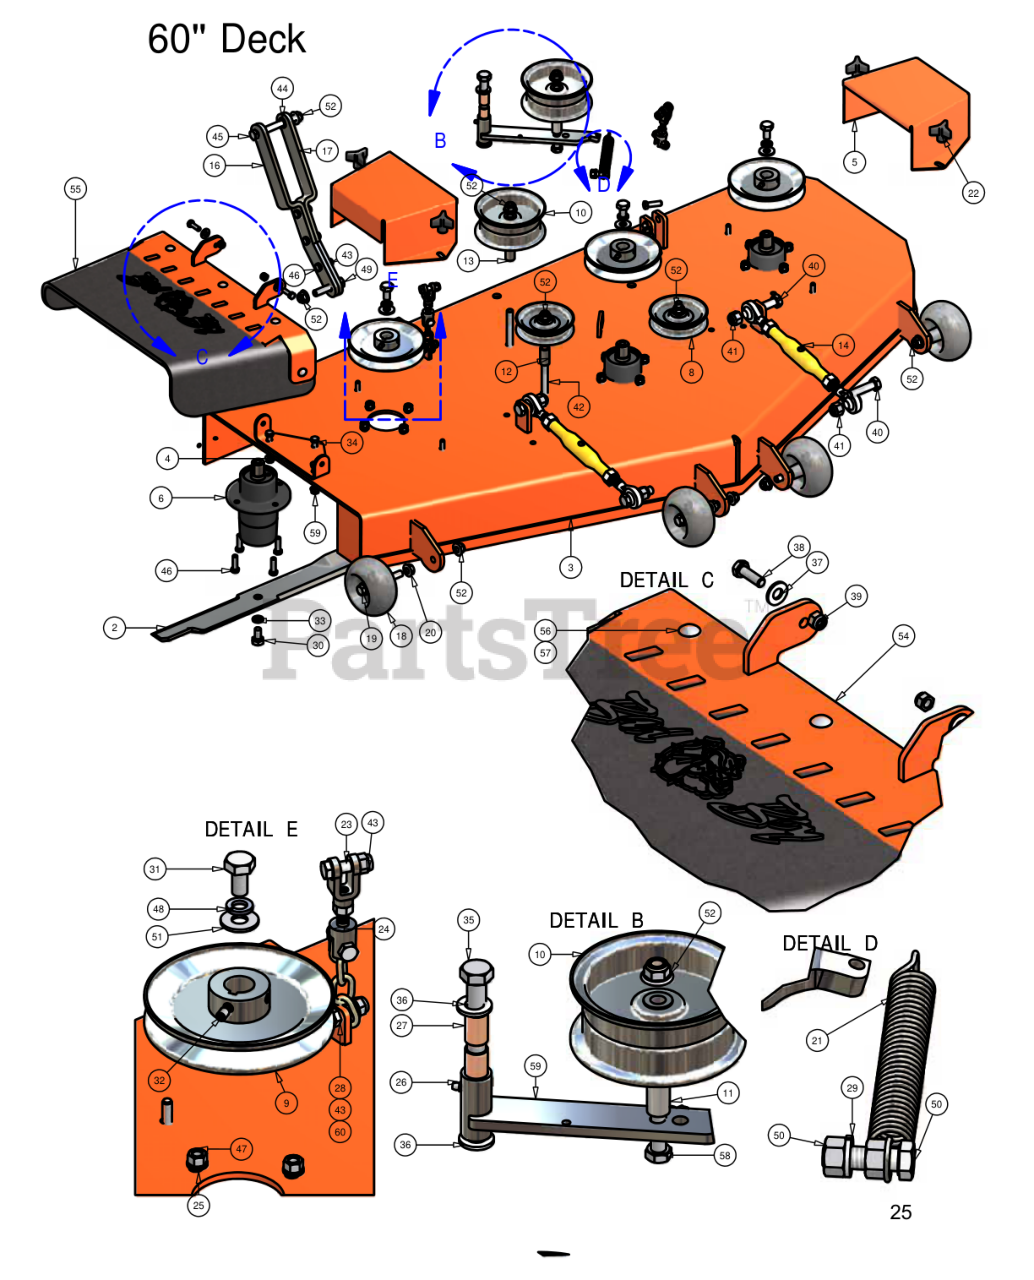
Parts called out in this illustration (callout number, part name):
1	60" Deck Belt
2	60" Fusion Blade
4	Discharge Chute Hanger
5	Pulley Guard
7	Deck Idler Arm
8	4 3/4" Idler Pulley
9	6 1/4" Drive Pulley
10	5 3/4" Flat Idler Pulley
11	1 1/4" Pulley Spacer
12	1 1/2" Pulley Spacer
13	1 3/4" Pulley Spacer
14	Turnbuckle
15	3/4" Left Handed Nut
16	Deck Support Arm (left)
17	Deck Support Arm (Right)
18	Anti-Scalp Rollers
19	1/2" x 4" Bolt (Grade 8)
20	1/2" Flange Nut
21	Deck Idler Spring
22	5/16" Knob
23	Female Yoke
26	Grease Fitting (Drive-In Type)
27	5/8" ID x 1 1/8" Brass Bushing
28	3/8" x 1" Hex Bolt
29	3/8" Lock Washer
30	5/8" x 1.5" Fine Threaded Bolt
31	1/2" x 1 1/2" Bolt (Fine Threaded)
32	3/8" Set Screw
33	5/8" Lock Washer
34	3/8" x 3/4" Hex Bolt
35	5/8" x 4" Hex Bolt
36	.635 ID Plastic Washer
37	.360 ID Plastic Washer
38	5/16" x 1" Hex Bolt
39	5/16" Nylock Nut
40	5/8" x 2 1/2" Hex Bolt
41	5/8" Nylock Nut
42	1/2" x 3 1/2" Bolt
43	3/8" Nylock Nut
44	1/2" Brass Washer
45	1/2" x 4 1/2" Bolt
46	3/8" x 1 1/4" Hex Bolt
47	3/8" Hex Nut
48	1/2" Lock Washer
49	1/2" x 2 1/2" Hex Bolt
50	3/8" x 1 1/2" Hex Bolt
51	1/2" Cupped Washer
52	1/2" Flange Lock Nut
53	2007 Lower Hanger Plate
54	2007 Hanger Plate
55	Rubber Side Discharge
56	5/16" x 1 1/2" Carriage Bolt
57	5/16" Nylock Flange Nut
58	1/2" x 3" Bolt
59	3/8" Flange Nut
60	3/8" Flat Washer
